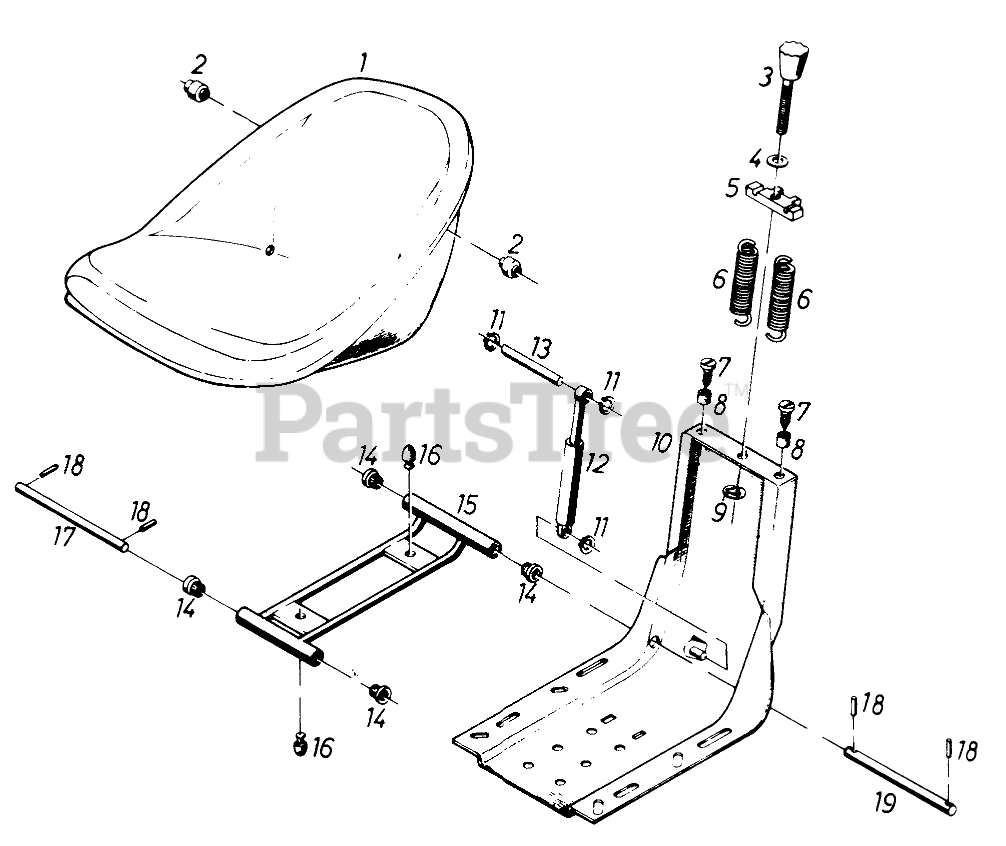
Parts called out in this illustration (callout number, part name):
2	Roller
3	Adjusting Spindle
4	Washer
5	Spring Support
6	Tension Spring
7	Screw
8	Limiting Devise
9	Grip Ring
10	Seat Support
11	Grip Ring
12	Shock Absorber
13	Spindle
15	Seat Carrier
16	Limiting Devise
17	Spindle
19	Spindle
